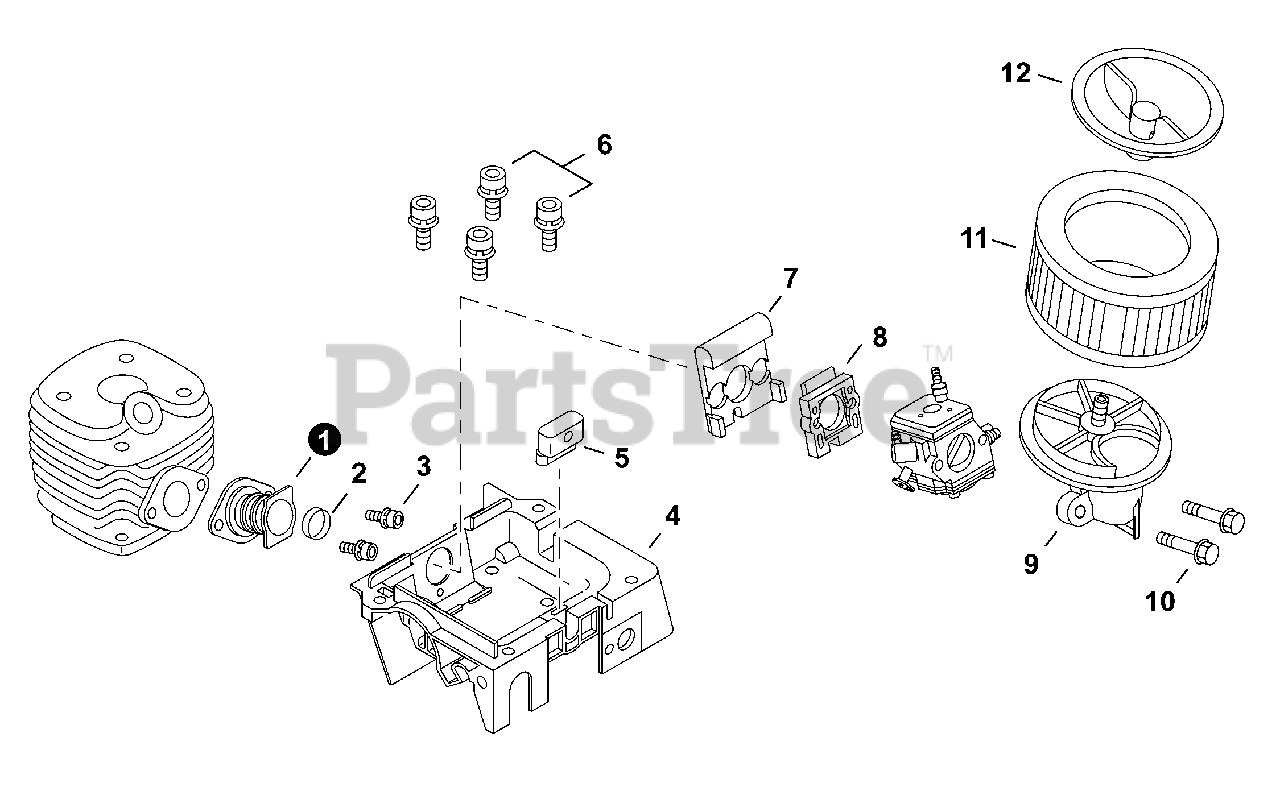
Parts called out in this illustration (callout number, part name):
1	BELLOWS, INTAKE
2	COLLAR 18.6×20.4×4
3	BOLT 5×14
4	CASE, CARBURETOR
5	CUSHION
6	BOLT 5×20
7	CUSHION
8	INSULATOR, INTAKE
9	MOUNT, AIR FILTER
10	BOLT, FLANGE
11	FILTER, AIR
12	COVER, AIR FILTER
